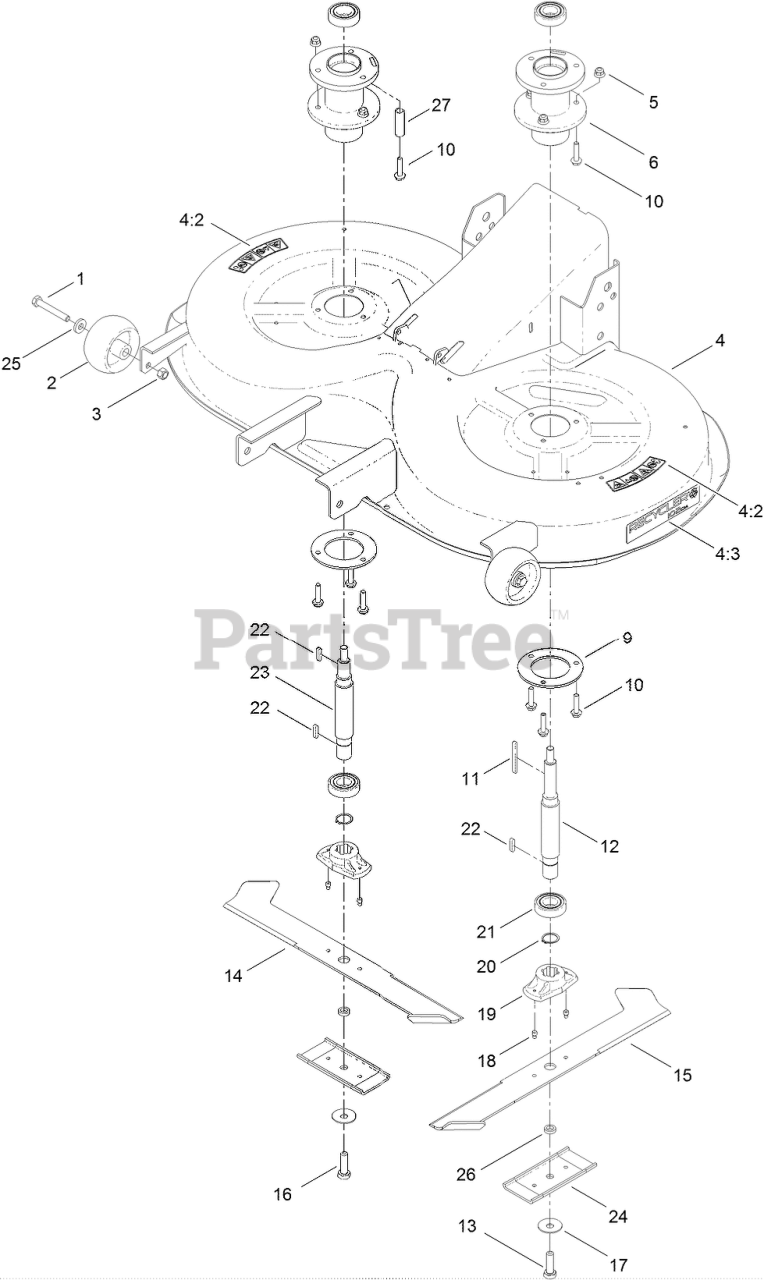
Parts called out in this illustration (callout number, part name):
1	SCREW-HH
2	WHEEL-GAUGE
3	NUT-LOCK, NI
4	DECK-ASSEMBLY, COMPLETE
4:2	DECAL-DANGER
4:3	DECAL-RECYCLER
5	NUT-LOCK, HHF
6	HOUSING-SPINDLE
9	SUPPORT-RING
10	BOLT-HHF
12	Shaft-Blade, LEFT
13	BOLT-HH
14	BLADE-RH
15	BLADE-LH
16	BOLT-BLADE, HH
17	WASHER-BLADE
18	PIN-SHEAR, GROOVED
19	Adapter-Blade
20	RING-LOCKING
21	BEARING-BALL
22	KEY-SQUARE
23	Shaft-BLADE, Right
24	STIFFENER-BLADE
25	WASHER-FLAT
26	Spacer
27	SPACER
